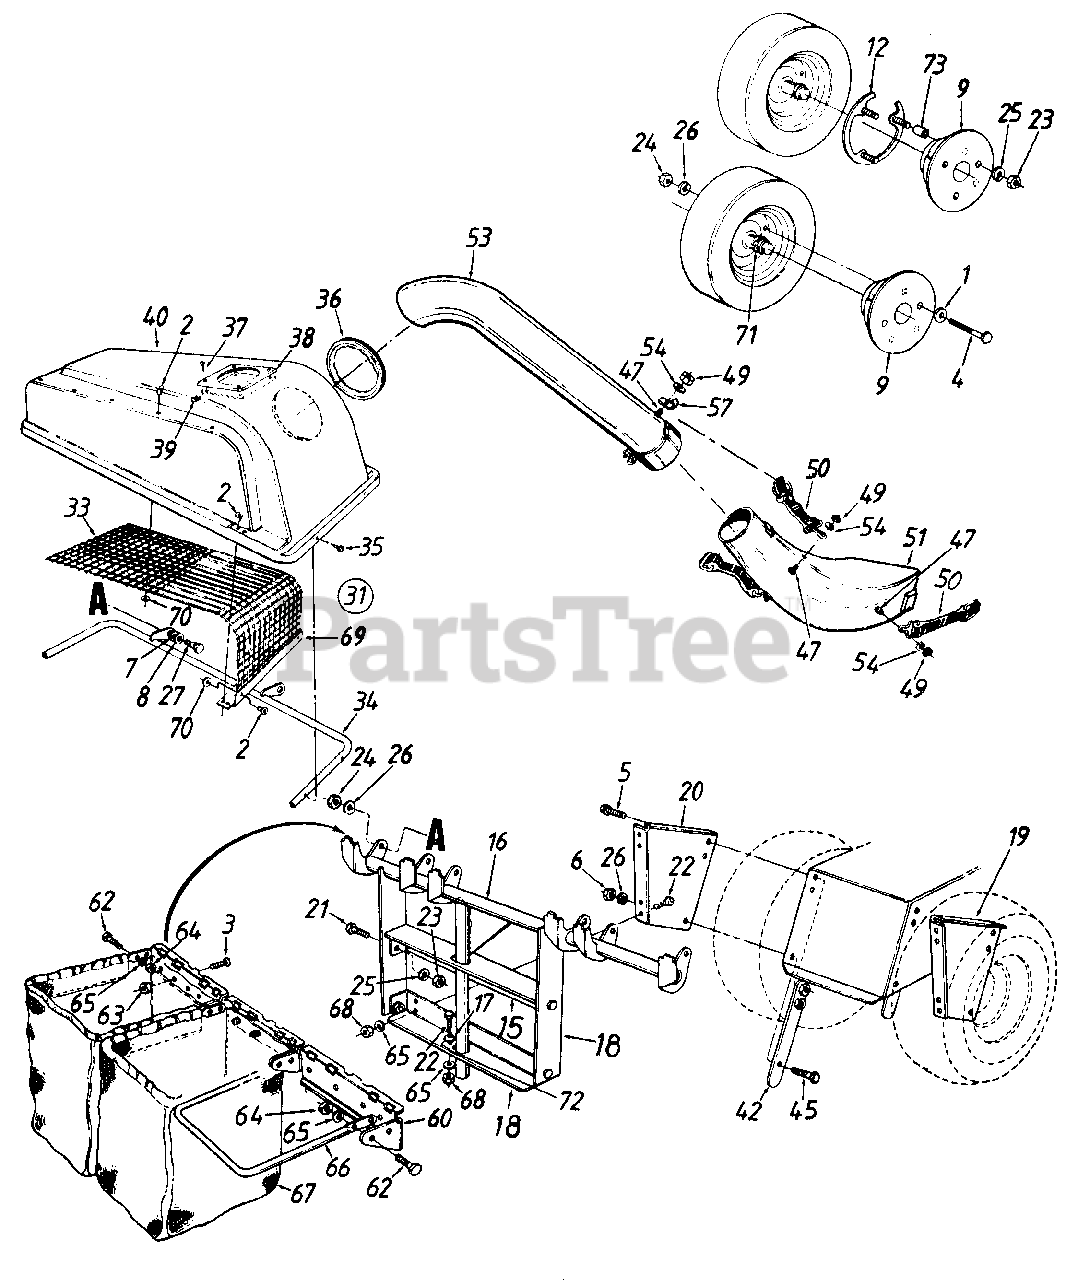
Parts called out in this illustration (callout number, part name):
1	Fl-Wash. .385" I.D.
2	Pop Rivet
3	Truss Mach. Scr. #10-24 x .38" Lg.
4	Hex Bolt 3/8-16 x 4.5" Lg.
5	Hex Wash. Hd. Tap Scr. 5/16-18 x .62"
6	Hex Nut 3/8 24 Thd.
7	Bell-Wash..515" I.D.
8	Fl-Wash. .510" I.D.
9	Wheel Weight
12	Wheel Weight Snap Ring
15	Catcher Support Tube Mtg. Brkt .
18	Catcher Latch and Support Brkt.
22	Hex Bolt 1/4-20 x .62" Lg.- Grade 5
23	Hex Nut 5/16-18 Thd.
24	Hex Nut 3/8-16 Thd.
25	L-Wash. 5/16" I.D.'
26	L-Wash. 3/8" I.D.
27	Shld. Bolt 3/8-16 x .500" Dia.
31	Grass Catcher Cover Ass'y. Comp.
33	Screen
36	Tube Seal
37	Truss Mach. B-Tap Scr. #10 x.5" Lg.
38	Plastic Plate
39	Speed Nut
40	Grass Catcher Cover
47	Hex Bolt 1/4-20 x .50" Lg.
49	Hex Ins. L-Nut 1/4-20 Thd.
50	Retainer Strap Ass'y.
51	Discharge Chute
53	Catcher Elbow Tube
54	L-Wash. .270" I.D. x .57" O.D.
57	Retainer Hook Brkt.
62	Hex Bolt 1/4-28 x .75" Lg.
63	Hex Sems Nut #10-24 Thd.
64	Hex Nut 1/4-28 Thd.
65	L-Wash. 1/4" I.D.
66	Catcher Bag Frame
67	Grass Catcher Bag
68	Hex Nut 1/4-20 Thd.
71	Foam Strip 1-1/8" x 1-1/2" x 3l8"
73	Spacer
